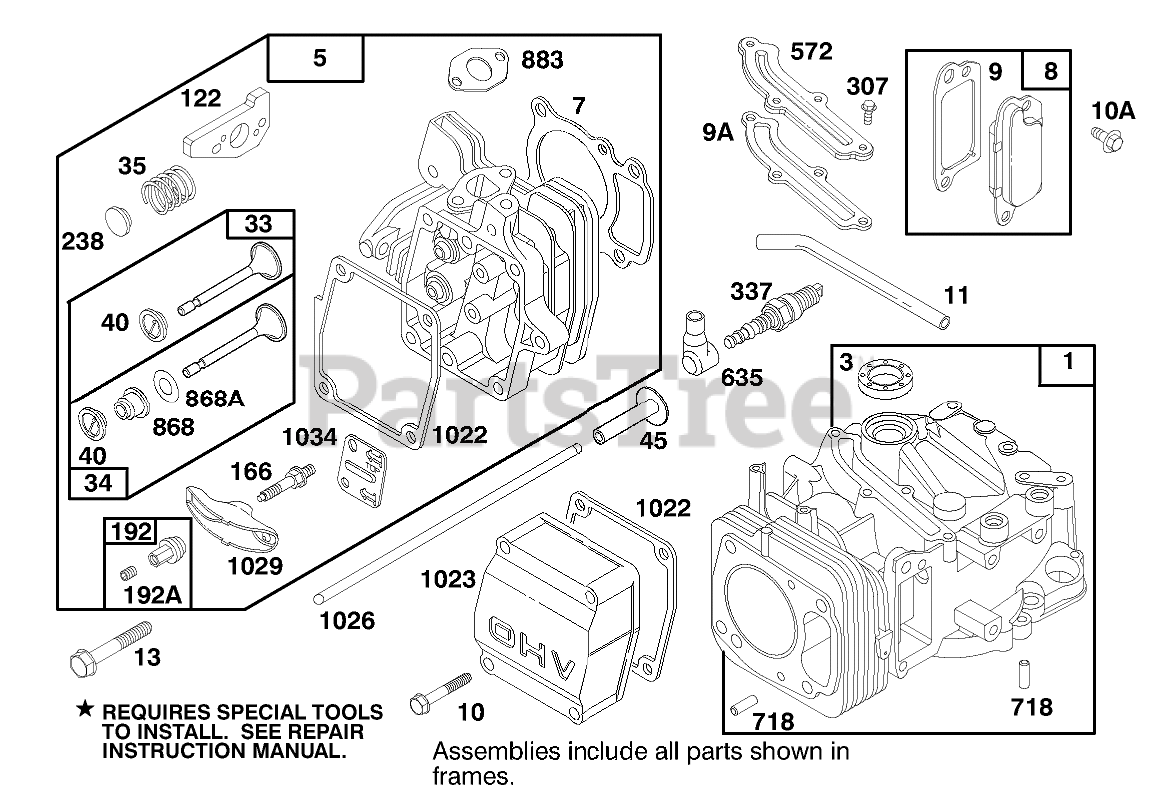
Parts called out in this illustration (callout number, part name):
1	CYLINDER ASSEMBLY
3	SEAL - OIL
5	CYLINDER HEAD
7	CYLINDER HEAD GASKET
8	BREATHER ASM
9	BREATHER GASKET
9A	GASKET-BREATHER
10	HEX HEAD SCREW
10A	HEX HEAD SCREW
11	TUBE - BREATHER
13	CYLINDER HEAD SCREW
33	EXHAUST VALVE
34	INTAKE VALVE
35	VALVE SPRING
40	SPRING RETAINER
45	VALVE TAPPET
122	ADAPTER ASSEMBLY
166	ROCKER ARM STUD
188	SCREW - SEM
192	NUT - HEX SPECIAL
192A	Screw-Set
238	VALVE CAP
307	SCREW - SEM
337	PLUG-SPARK
572	BAFFLE - CYCLINDER
635	SPARK PLUG ELBOW
718	DOWEL - SLEEVE
868	SealAssy-Valve
868A	Seal-Valve
883	EXHAUST GASKET
1022	ROCKER COVER GASKET
1023	COVER - VALVE
1026	PUSH ROD
1029	ROCKER ARM
1034	PUSH ROD GUIDE
